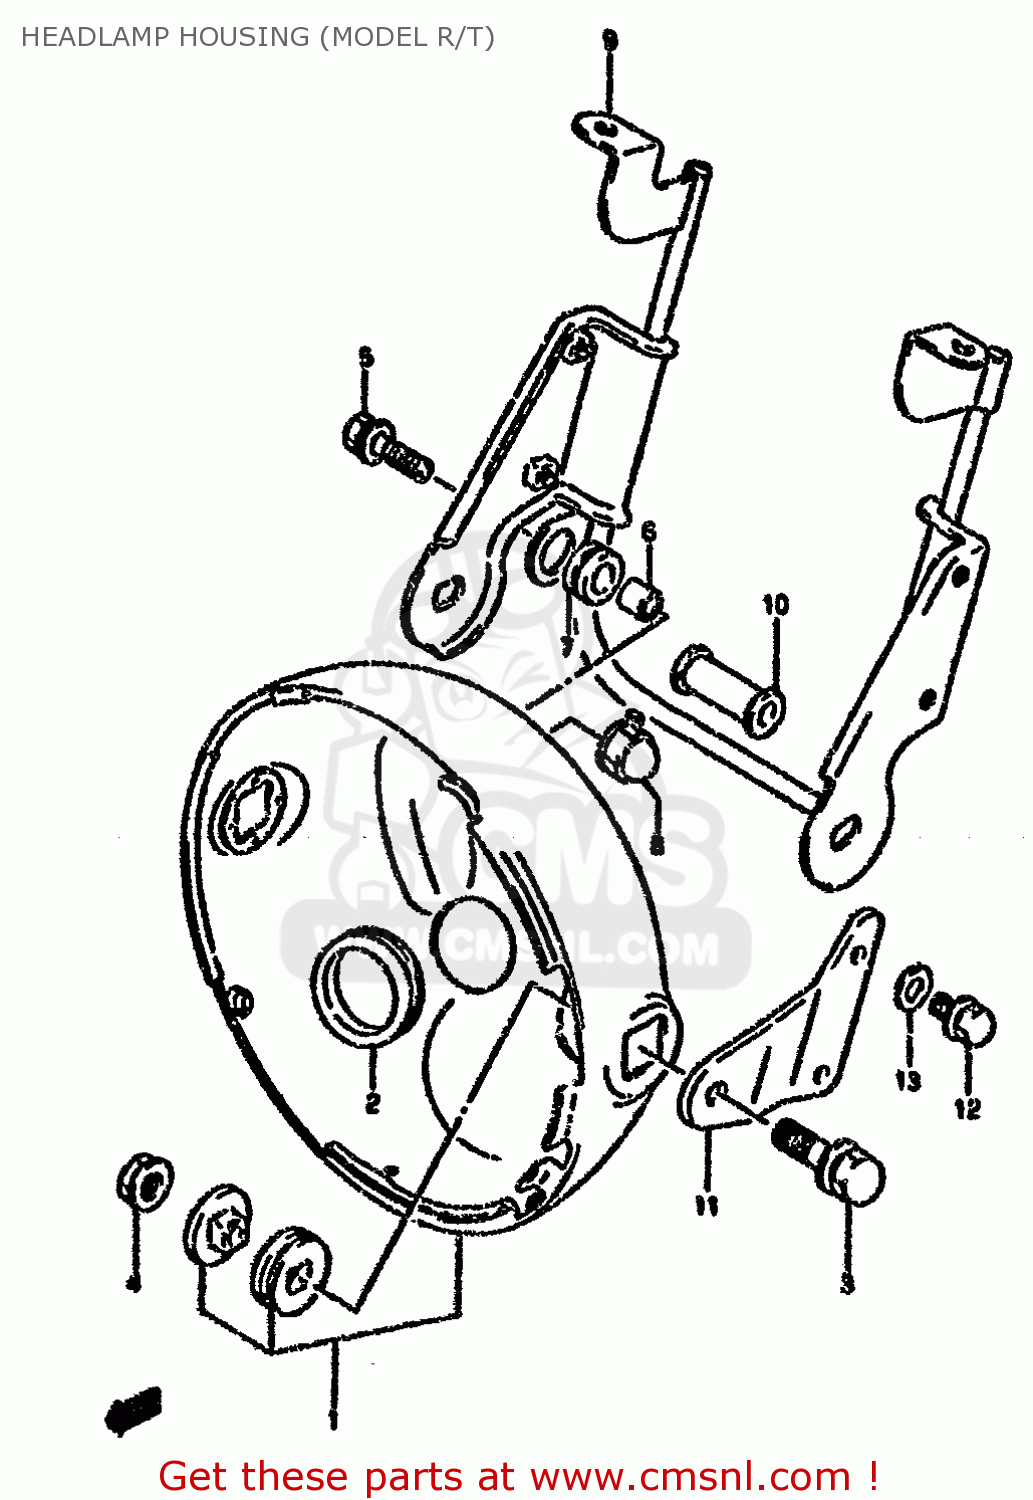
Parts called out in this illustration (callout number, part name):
1	HOUSING,HEADLAMP
2	GROMMET
3	BOLT
4	NUT
5	BOLT
6	SPACER(6.5X10.5X12)
7	CUSHION
8	PLATE,HEADLAMP
9	BRACKET,HEADLAMP
10	WASHER
11	BOLT
12	BOLT
13	WASHER
14	CUSHION
15	PLATE,HEADLAMP
